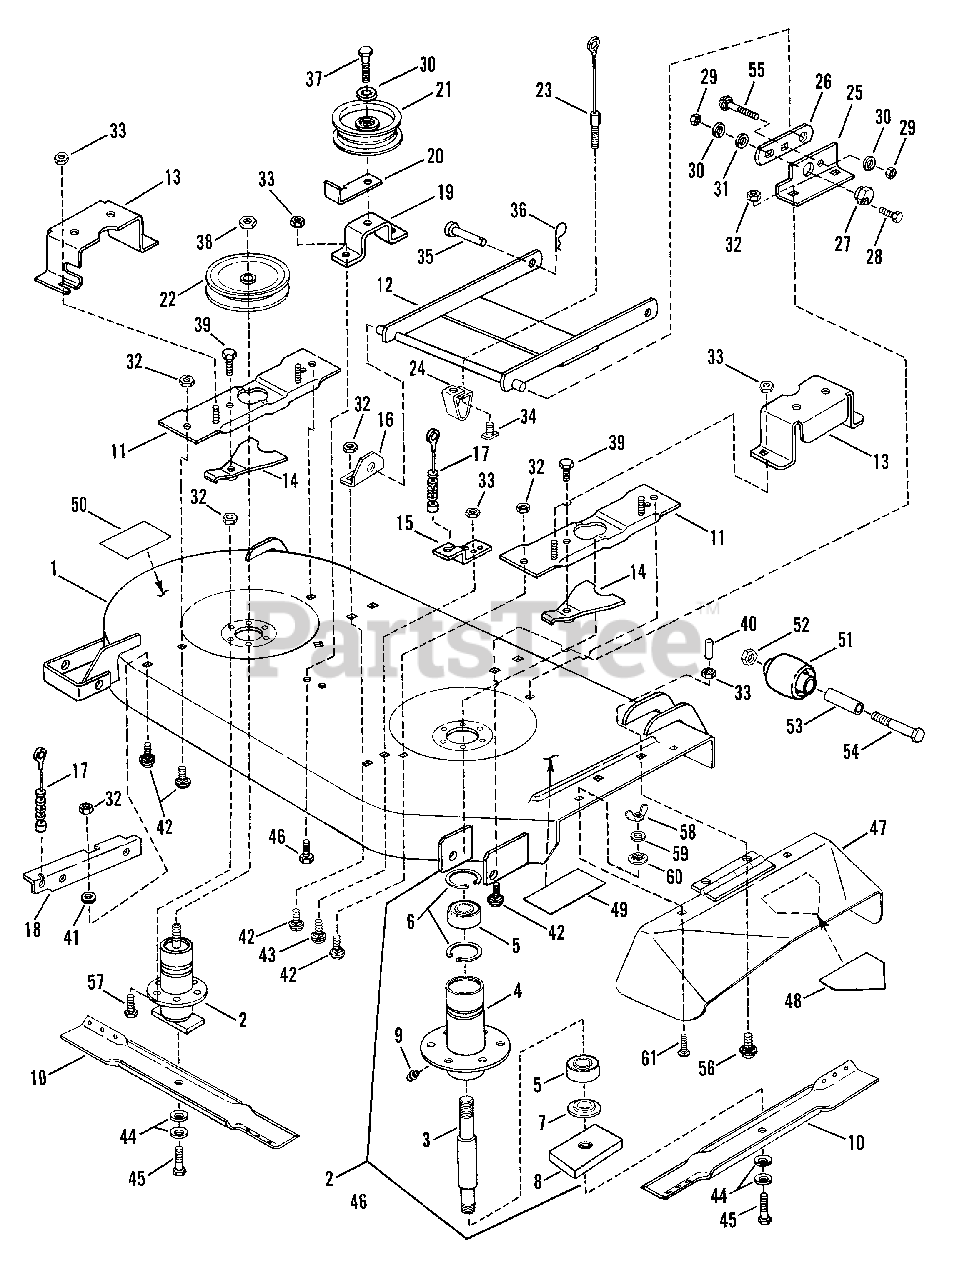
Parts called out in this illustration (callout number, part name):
1	DECK, Mower 41"
2	ASSEMBLY, Spindle
3	SPINDLE 6.5"
4	HOUSING, Spindle
5	BEARING, Spindle
6	RING, Retaining
7	WASHER, Spindle
8	HOLDER, Blade
9	FITTING, Lube (Press fit for .187 hole-no ball)
10	BLADE, 21" Cutter
11	ASSEMBLY, Rear Support
12	ASSEMBLY, Front Hanger
13	GUARD, Pulley
14	ASSEMBLY, Spindle Lock
15	ASSEMBLY, Chain Support
16	BRACKET, Front Left Hanger
17	CABLE, Support 4.25", 8 Spacers
18	ASSEMBLY, Rear Support
19	BRACKET, Idler Mount
20	GUIDE, Belt
21	PULLEY, Idler
22	PULLEY, Spindle
23	CABLE, Front Lift
24	BRACKET, Front Lift Arm Hanger
25	BRACKET, Front Right
26	LINK, Adjustment
27	RING, Adjustment
28	SCREW, 3/8-16 x 1" Hex Head Cap
29	NUT, 3/8-16 Hex
30	WASHER, 3/8" Split Lock
31	WASHER, 3/8" Flat
32	NUT, 3/8-16 Hex Flange Lock
33	NUT, 5/16-18 Hex Flange Lock
34	T-NUT, 5/16-18
35	PIN, 1/2 x 1-3/8" Clevis
36	HAIRPIN, Cotter
37	SCREW, 3/8-16 x 1-1/2" Hex Cap
38	NUT, 3/4-16 Hex Jam
39	BOLT, 3/8-16 x 1" Hex Flange Lock
40	CAP, Vinyl
41	WASHER, 7/16 Flat
42	BOLT, 3/8-16 x 3/4" Carriage
43	BOLT, 5/16-18 x 3/4" Carriage
44	WASHER, 13/32 x 1-13/32" Dia. Cone
45	SCREW, 3/8-24 x 1-1/4" Hex Cap
46	BOLT, 5/16-18 x 3/4" Hex Flange Lock
47	DEFLECTOR, Side Chute
48	DECAL, Danger
49	DECAL, Caution (Deflector in Place)
50	DECAL, Caution (Rotating Blades)
51	WHEEL, Gage
52	LOCKNUT, 3/8-24 Hex
53	SPACER
54	SCREW, 3/8-24 x 3-3/4" Hex Hd. Cap
55	BOLT, 3/8-16 x 3/4" Short Neck Carriage
56	BOLT, 5/16-18 x 1" Short Neck Carriage
57	BOLT, 3/8-16 x 3/4" Hex Flange Lock
58	WING-NUT, 5/16-18
59	WASHER, 5/16 Split Lock
60	RETAINER, 5/16 Bolt
61	BOLT, 5/16-18 x 5/8" Carriage
